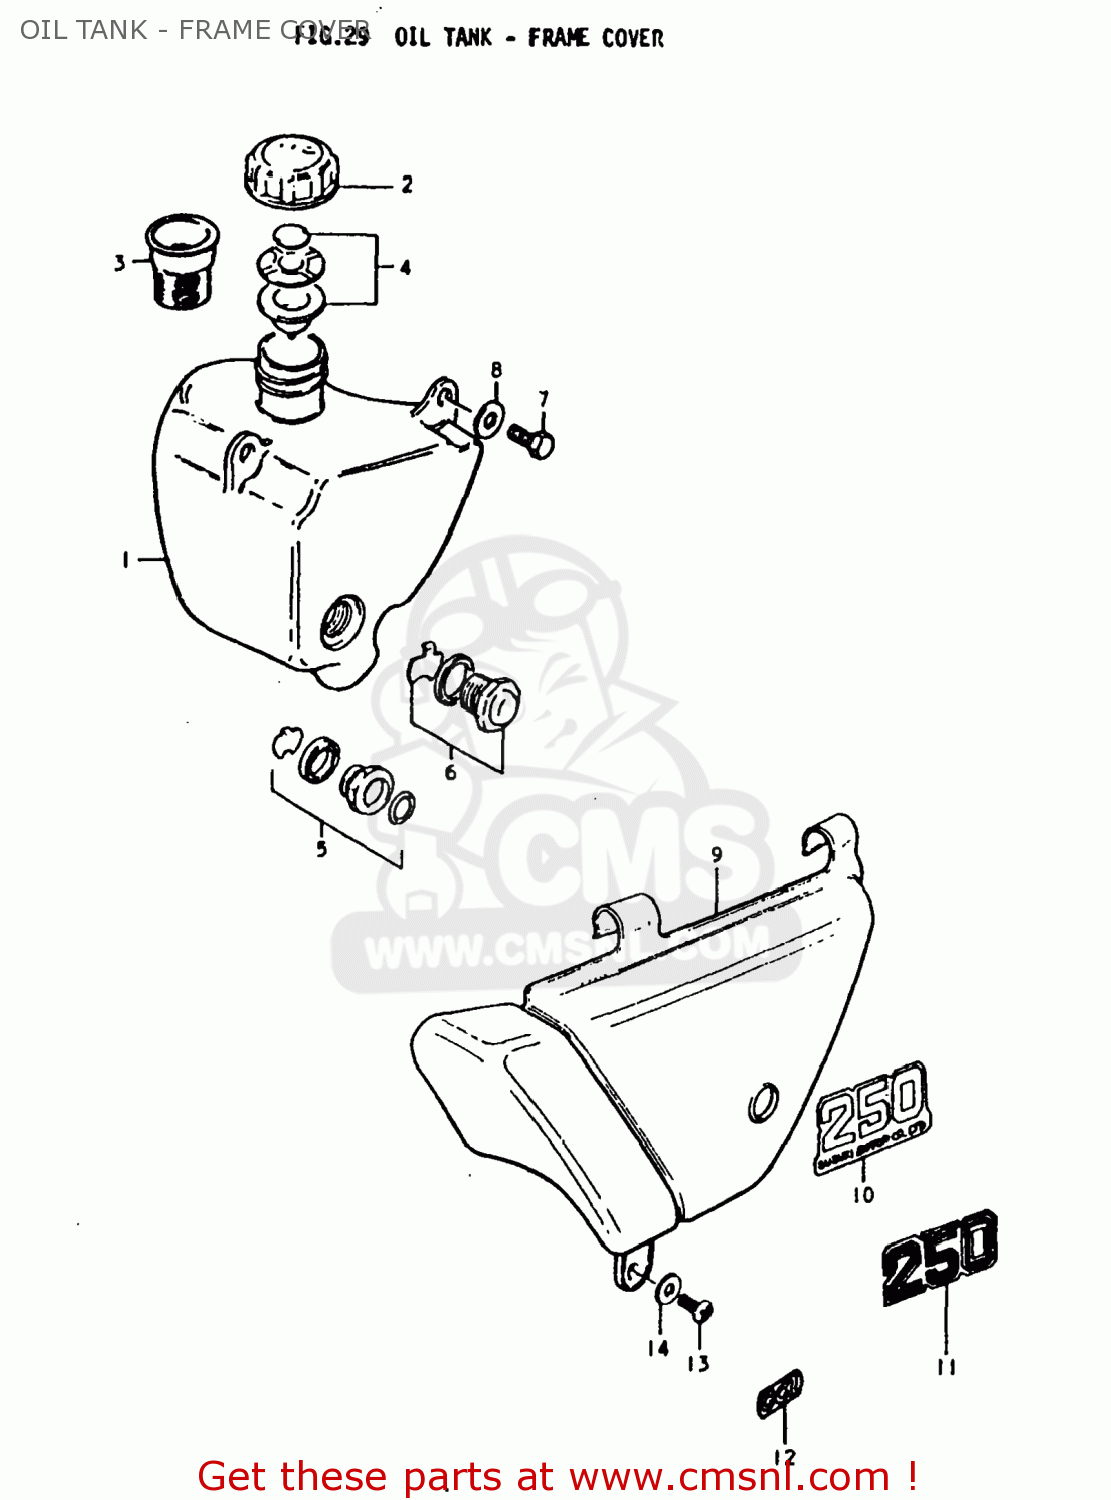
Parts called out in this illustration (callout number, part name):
1	TANK,OIL
2	CAP,OIL TANK
3	FILTER,OIL TANK INLET
4	GASKET SET
5	LENS SET,OIL LEVEL
6	LENS SET,OIL LEVEL
7	BOLT, UPPER
8	WASHER
9	COVER,FRAME,LEFT
10	EMBLEM,FRAME COVER
11	EMBLEM,FRAME COVER
12	EMBLEM,CCIS
13	SCREW 6X12
14	WASHER
